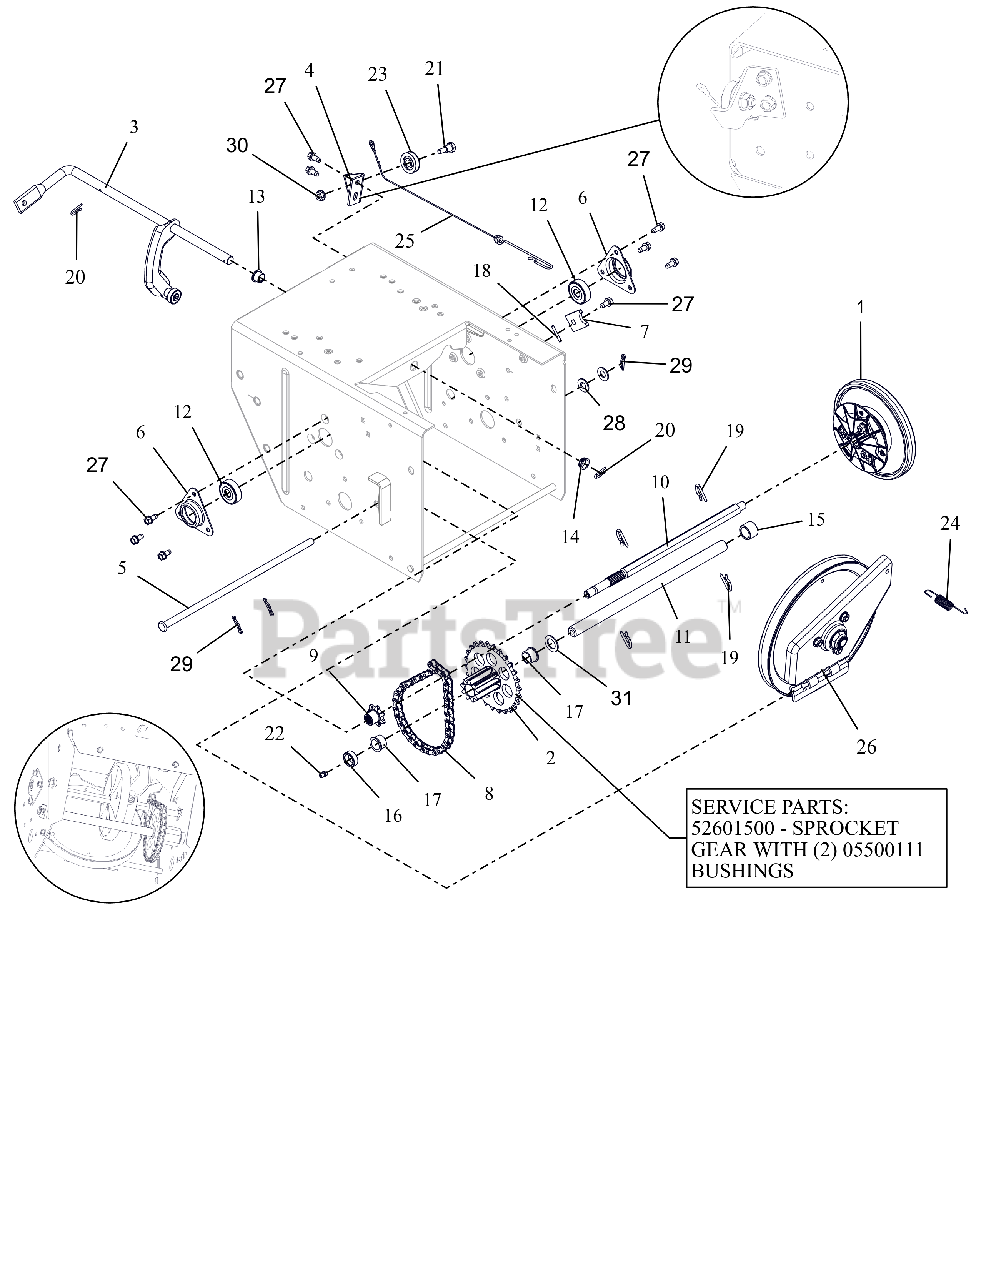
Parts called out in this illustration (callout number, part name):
1	DISC, FRICTION DRIVE-ASSEMBLY
2	PINION & SPROCKET
2	PINION & SPROCKET W/BUSHINGS
3	ARM, SHIFT-PRO (ASSEMBLY)
4	BRACKET, CABLE PULLEY
5	PIN, PIVOT
6	FLANGE, BEARING
7	TAB, ANTI ROTATION
8	CHAIN - #41, 32 PITCHES
9	SPROCKET, PINION 7T W/SPLINE
10	SHAFT, HEX - HEAT TREATED
11	SHAFT, PINION - HARDENED
12	BRG-BALL .437X1.375X.437
13	BUSHING, POLYLINER-.50 SPLIT
14	BUSHING, POLYLINER-.50 SNAPIN
15	SPACER, .635X.880X.611
16	BSHG-SLV, .635X.880X.305
17	BSHG-FLG .625X.750X.500X.875
18	PIN-ROLL .125X1.00
19	PIN, SPRING CLIP
20	CLIP, SPRING
21	BOLT, SHLDR-.375X.375X.25-20
22	ZERK,FITTING .25X.125 DRIVE IN
23	PULLEY, CABLE
24	SG-TENS .048X.50X2.8
25	CABLE, LOWER TRACTION,SS & PRO
26	PLATE, SWING ASSEMBLY-DEEP
27	SCR-TAP .25-20X.50 HWH ZCC
28	WSHR,FLT .406X.812X.065 ZCC
29	PIN, HAIR #225 .072X1.09
30	NUT-LK-TOP-FLG .250-20 GF ZCC
31	WSHR, FLT .630X1.005X.062 ZCC
